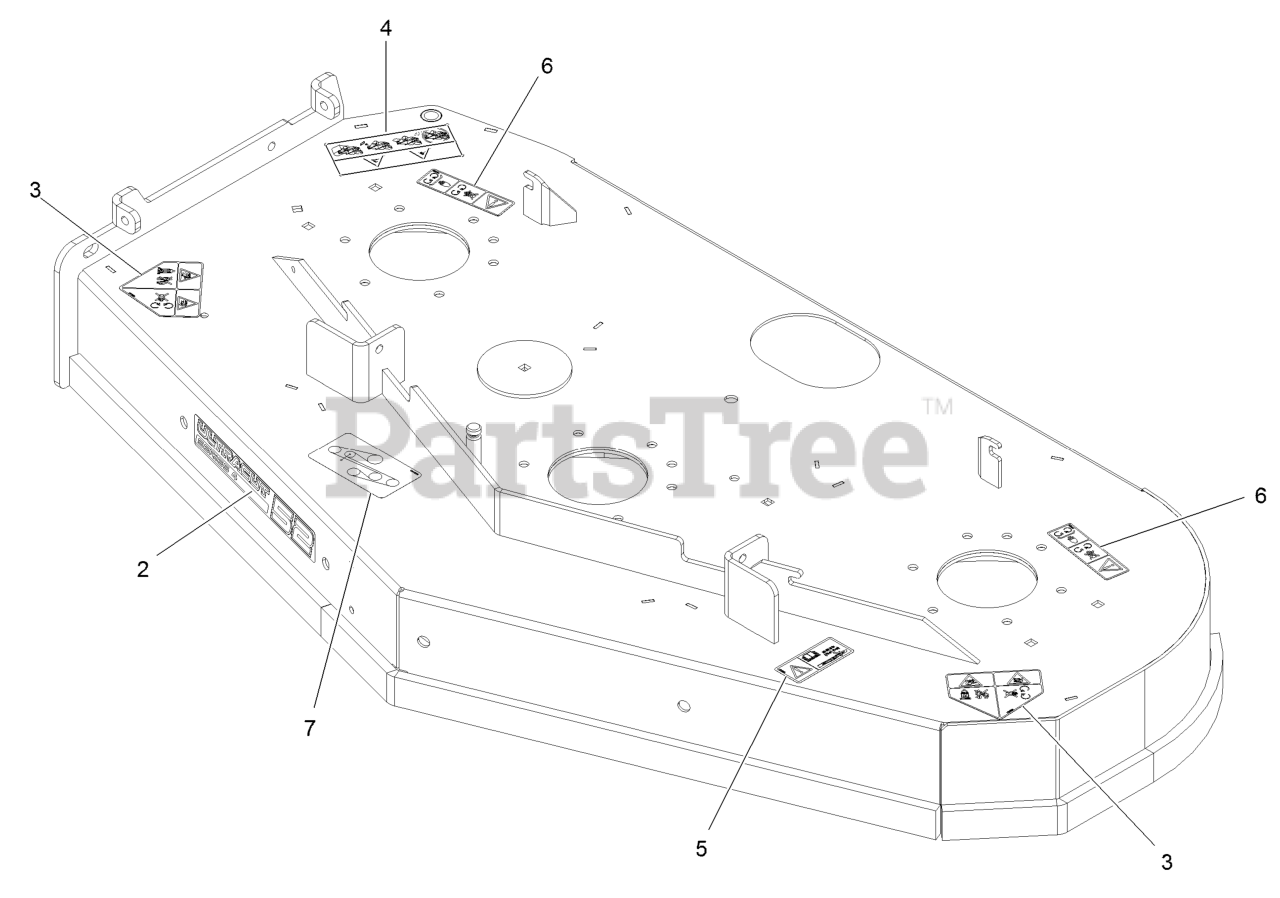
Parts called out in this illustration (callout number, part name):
2	DECAL, 524
3	DECAL-DANGER
4	DECAL-WARNING, BAGGER
5	DECAL-BOLT TORQUE
6	DECAL-COVER, MISSING
7	DECAL-BELT ROUTING
